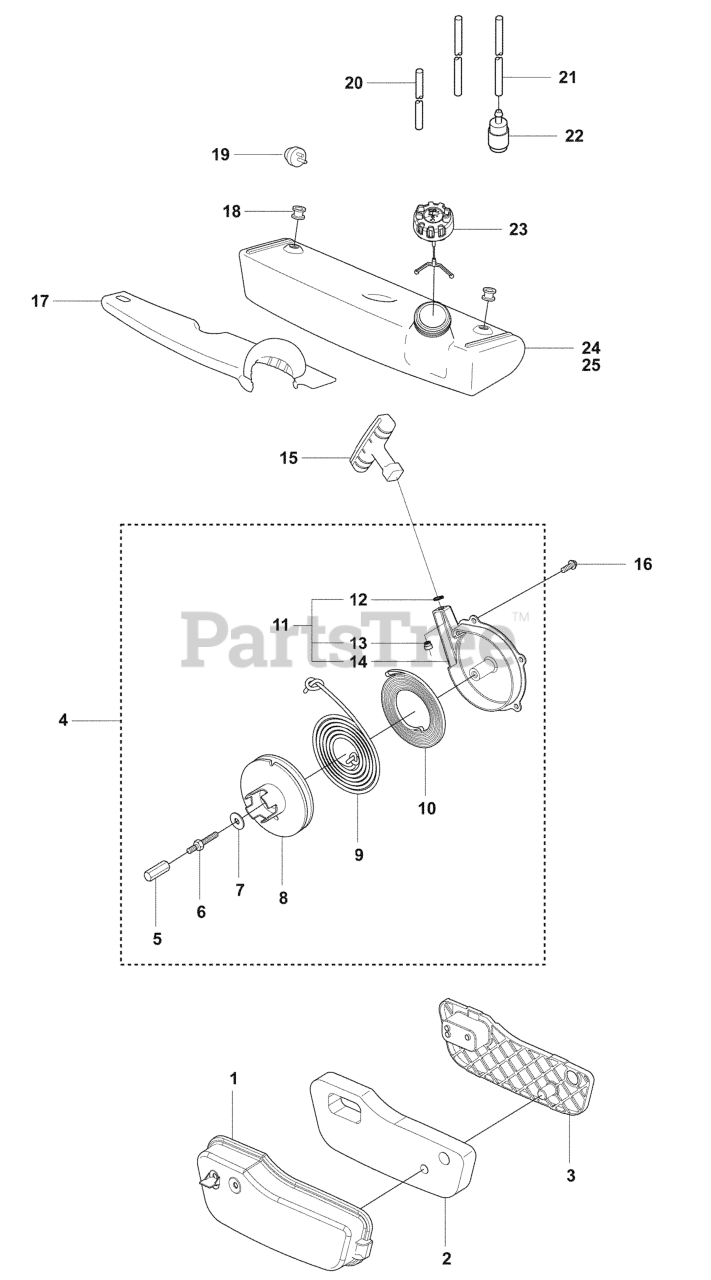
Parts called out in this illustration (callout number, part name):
2	AIR FILTER
3	NET AIR FILTER
4	STARTER DEVICE
8	STARTER PULLEY
9	STARTER ROPE
10	RECOIL SPRING
12	RETAINING RING
13	SLEEVE, STARTER HOUSING
14	STARTER DEVICE
15	STARTER HANDLE
18	FUEL TANK BUSHING
19	AIR PURGE BUBBLE
22	RP FUEL FILTER
23	FUEL CAP ASSY
